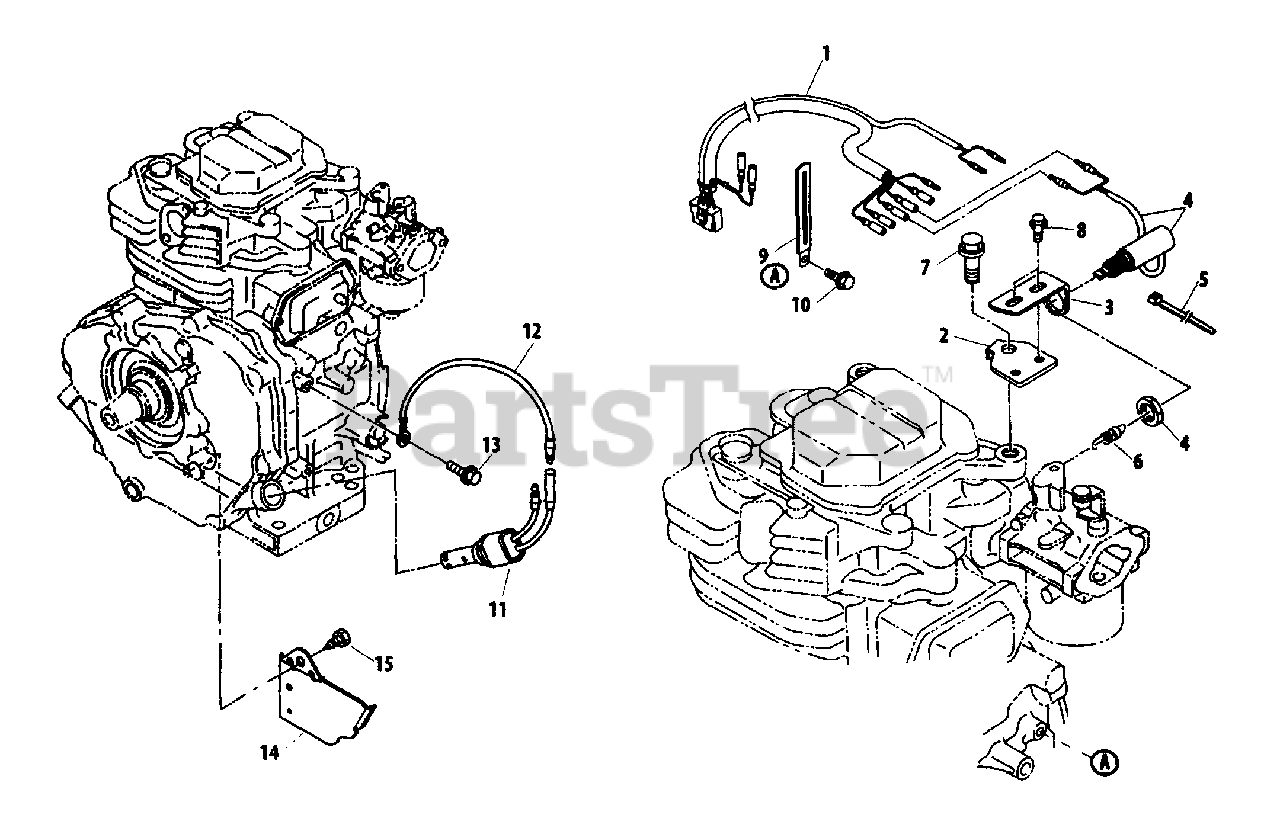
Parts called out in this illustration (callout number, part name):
1	WIRE - 19
2	BRACKET, SOLENOID 1
3	BRACKET, SOLENOID 2
5	BAND
6	SPRING (SOLENOID)
7	BOLT
8	BOLT
9	CLAMP
10	BOLT - FLANGE
11	OIL SENSOR ASSY
12	WIRE - 3
13	BOLT - FLANGE
14	PLATE
15	BOLT - TAPPING
